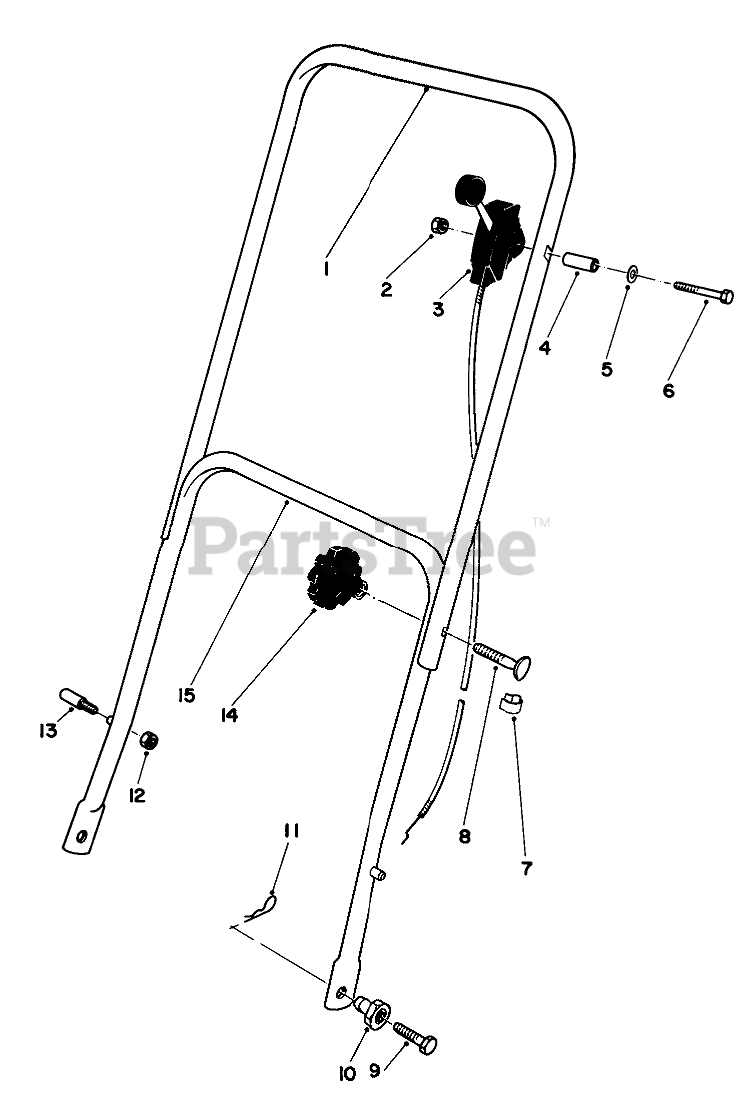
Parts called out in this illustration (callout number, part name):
1	UPPER HANDLE
2	NUT-LOCK, NI
3	SERVICE THROTTLE CONTRO
4	Spacer
5	WASHER
6	SCREW-HH
8	5/16-18 X 2 HNDLE SCREW
9	SCREW-HH
10	HANDLE PIVOT NUT
11	PIN-COTTER, HAIR
12	NUT-LOCK, NI
13	HANDLE PIN
15	LOWER HANDLE ASM
